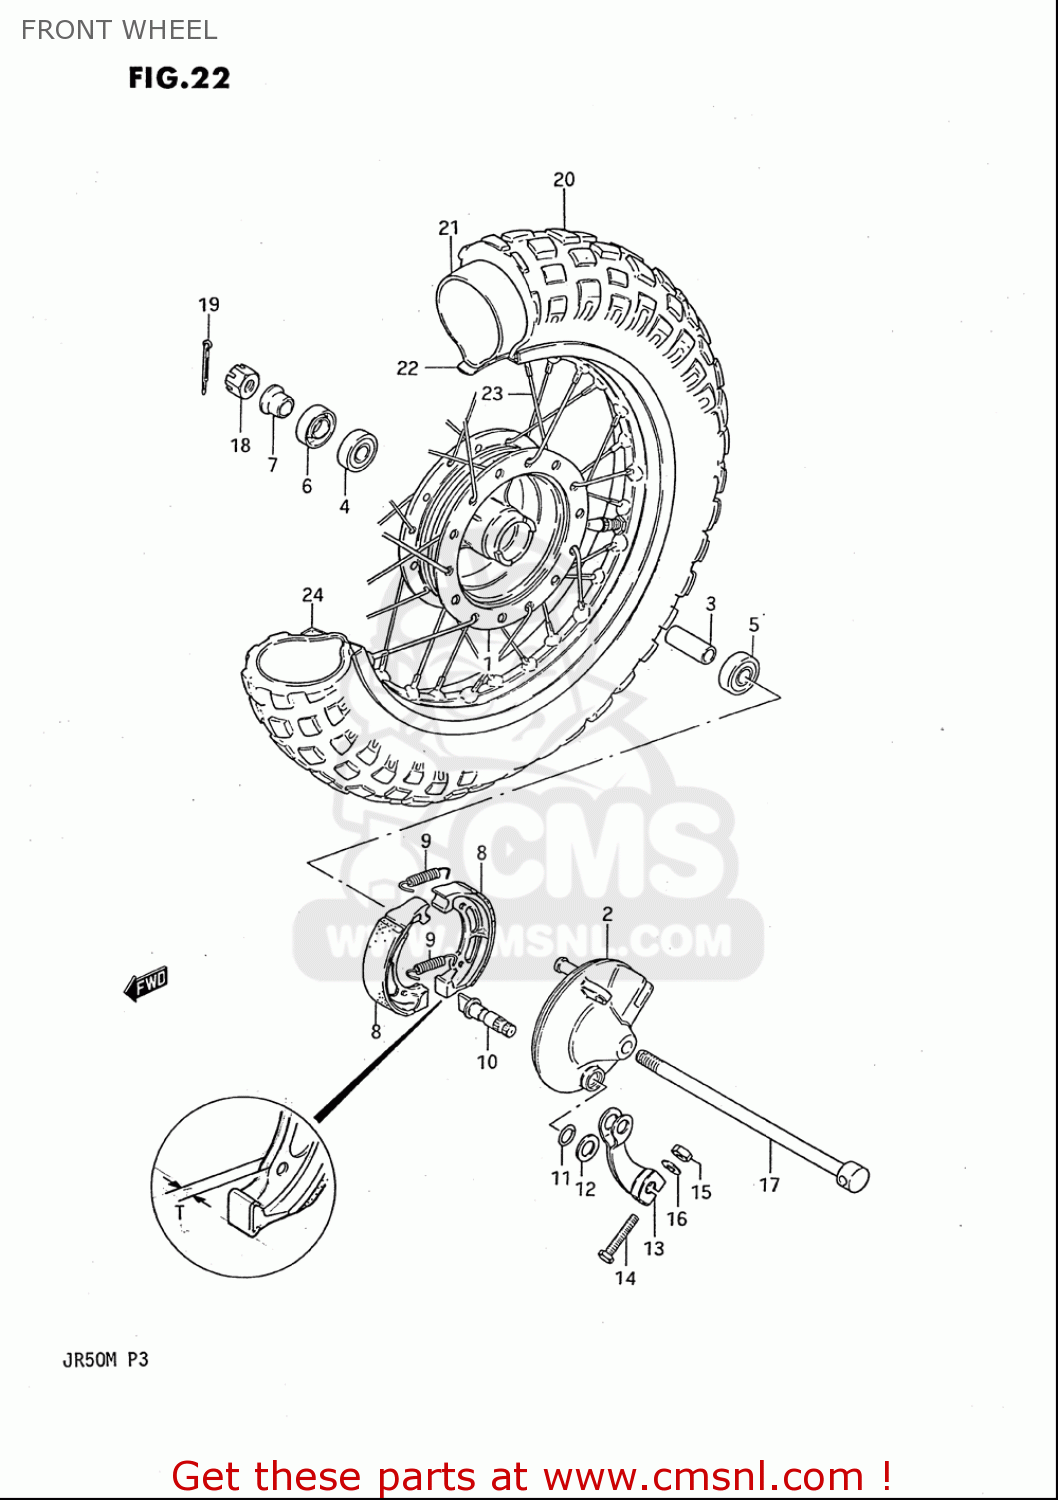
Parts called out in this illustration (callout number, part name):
1	HUB,FR WHEEL
2	PANEL,FR BRAKE ANCHOR
3	SPACER(10.2X16X47)
4	BEARING(10X26X8)
5	BEARING
6	SEAL,OIL(15X27X6)
7	SPACER,AXLE
8	SHOE & SPRING SET (NAS)
9	SPRING(L:35.8)
10	CAM,BRAKE
11	O RING(D:2.4,ID:9.6)
12	WASHER(10.5X18X1)
13	LEVER,FR BRAKE CAM
14	BOLT
15	NUT
16	WASHER
17	AXLE,RR
18	NUT
19	PIN
20	TIRE
21	TUBE,INNER
22	PROTECTOR,INNER TUBE
23	SPOKE SET,RR
24	RIM,WHEEL
